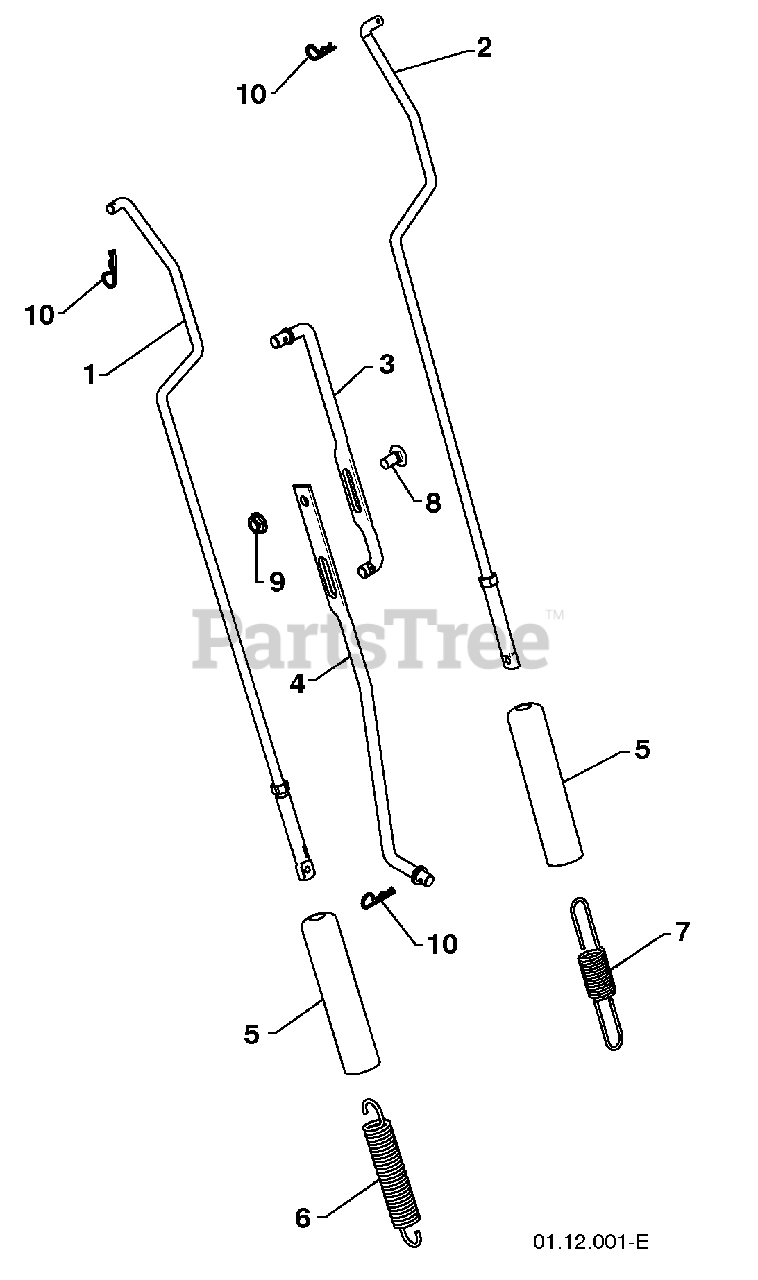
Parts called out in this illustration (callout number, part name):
1	IMPELLER ROD ASSEMBLY
2	TRACTION ROD ASSEMBLY
3	SHIFTER ROD TOP
4	SHIFTER ROD BOTTOM
5	SPRING SLEEVE
6	IMPELLER SPRING
7	TRACTION SPRING
8	CARRIAGE BOLT 5/16-18 X .75
9	NUT 5/16-18
10	RETAINER
